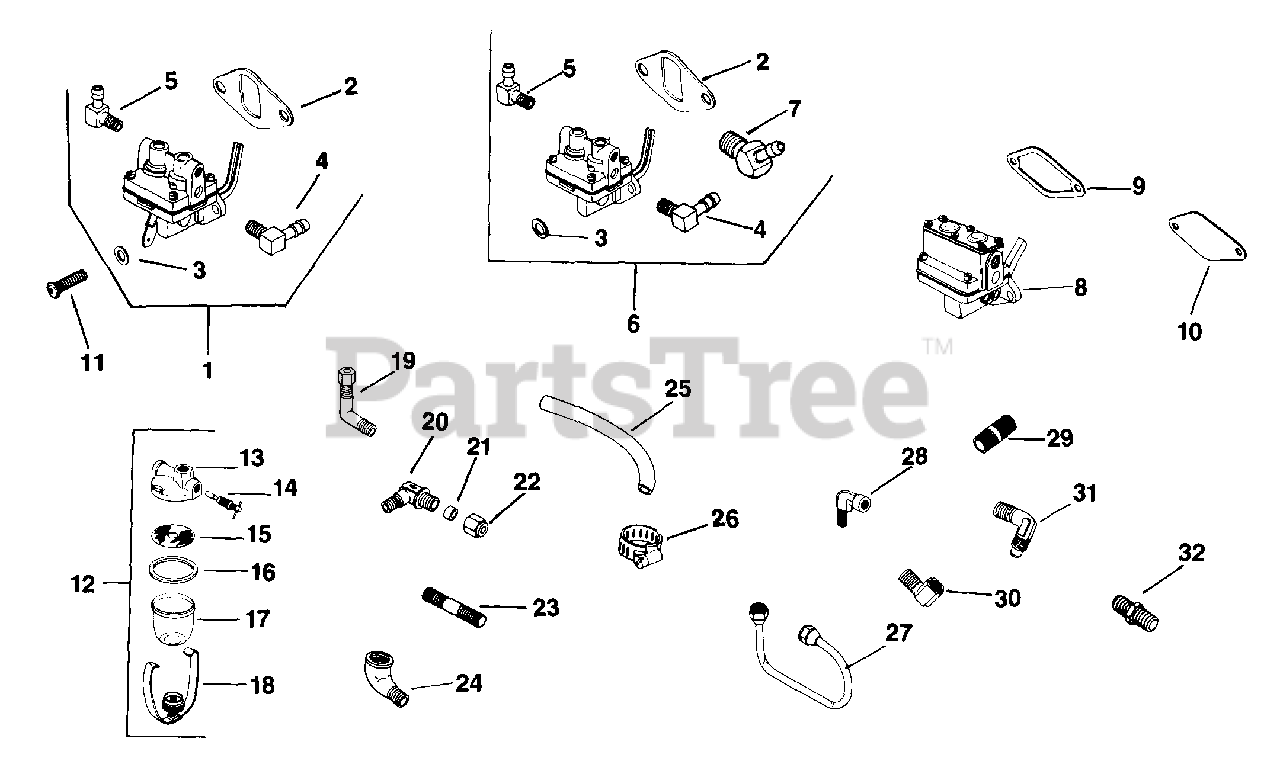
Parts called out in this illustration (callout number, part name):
2	GASKET - USE 25 041 09
3	WASHER, FLAT 1/4" (O.D. 1/2")
4	CONNECTOR, 90 DEG. HOSE
5	CONNECTOR, 90 DEG. - DISCONTINUED
7	CONNECTOR, 45 DEG.
11	SCREW, SEMS 1/4-20X3/4"
